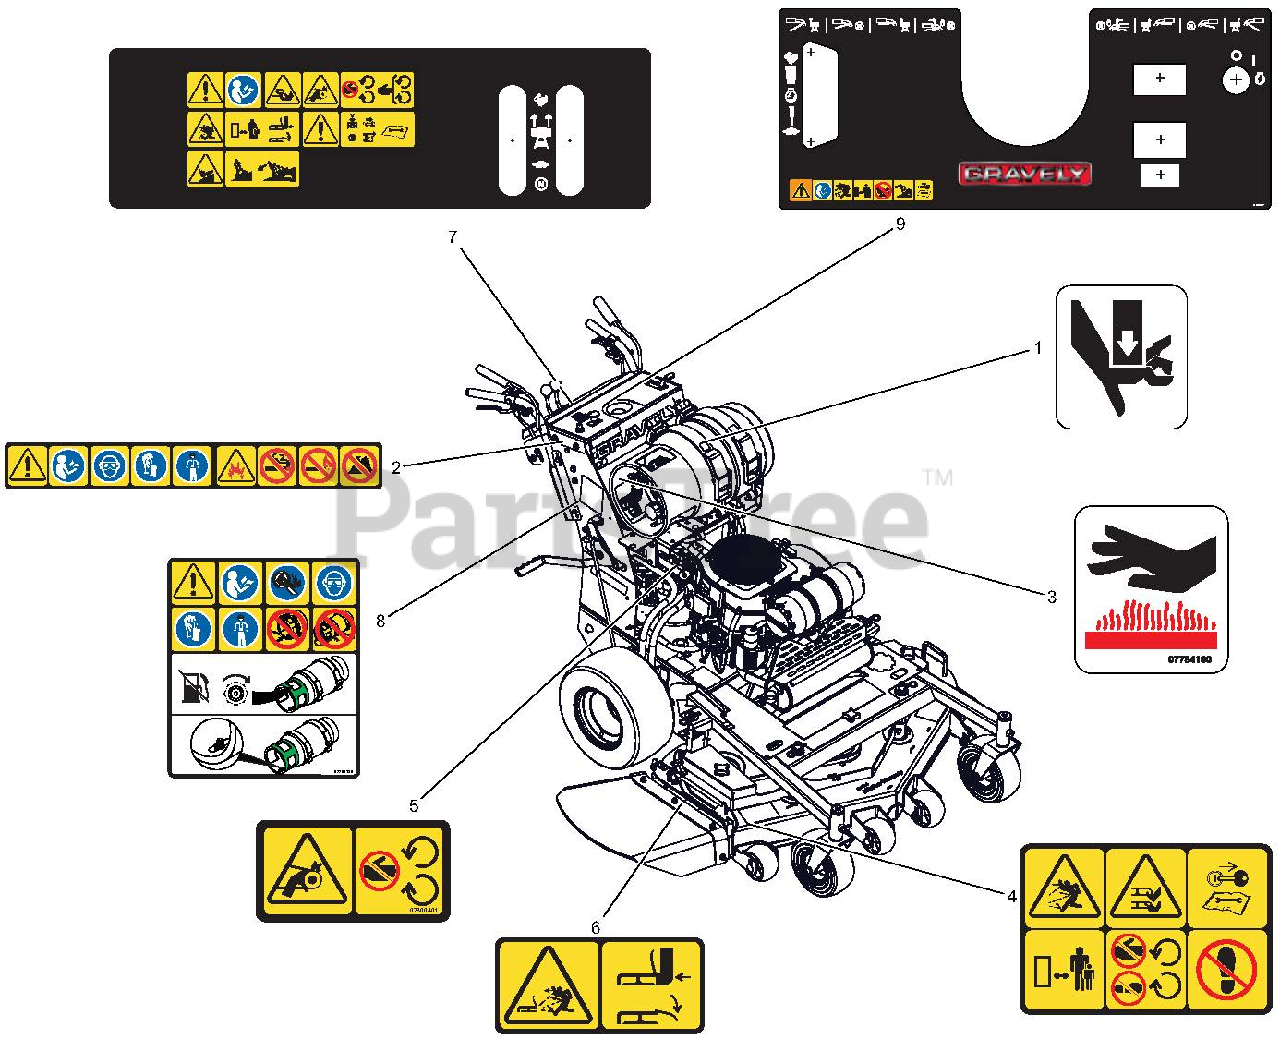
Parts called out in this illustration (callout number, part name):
1	DECAL, PINCH POINT
2	DECAL, SAFETY -LP
3	DECAL HOT SURFACE
4	DECAL, SAFETY - MOWER DECK
5	DECAL, SAFETY - GUARDING
6	DECAL, SAFETY - DECK GUARDING
7	DECAL, LOWER CONSOLE PG CE
8	DECAL, HORIZ MOWER TANKS ONLY
9	DECAL, CONSOLE GW LPG
